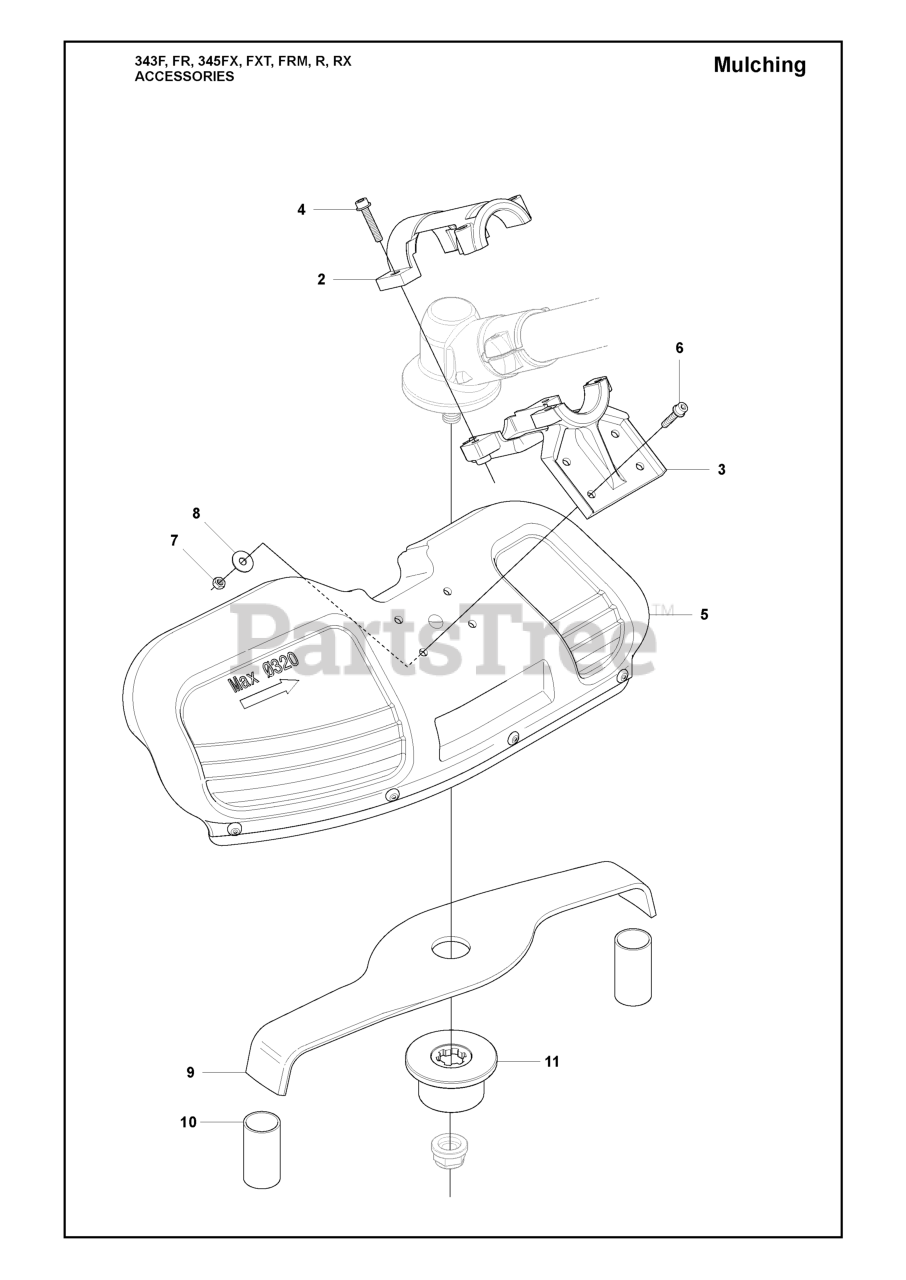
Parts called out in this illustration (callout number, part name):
5	SPRAY GUARD ASSY
7	LOCKNUT M5
10	TRANSPORT GUARD
11	SUPPORT FLANGE
